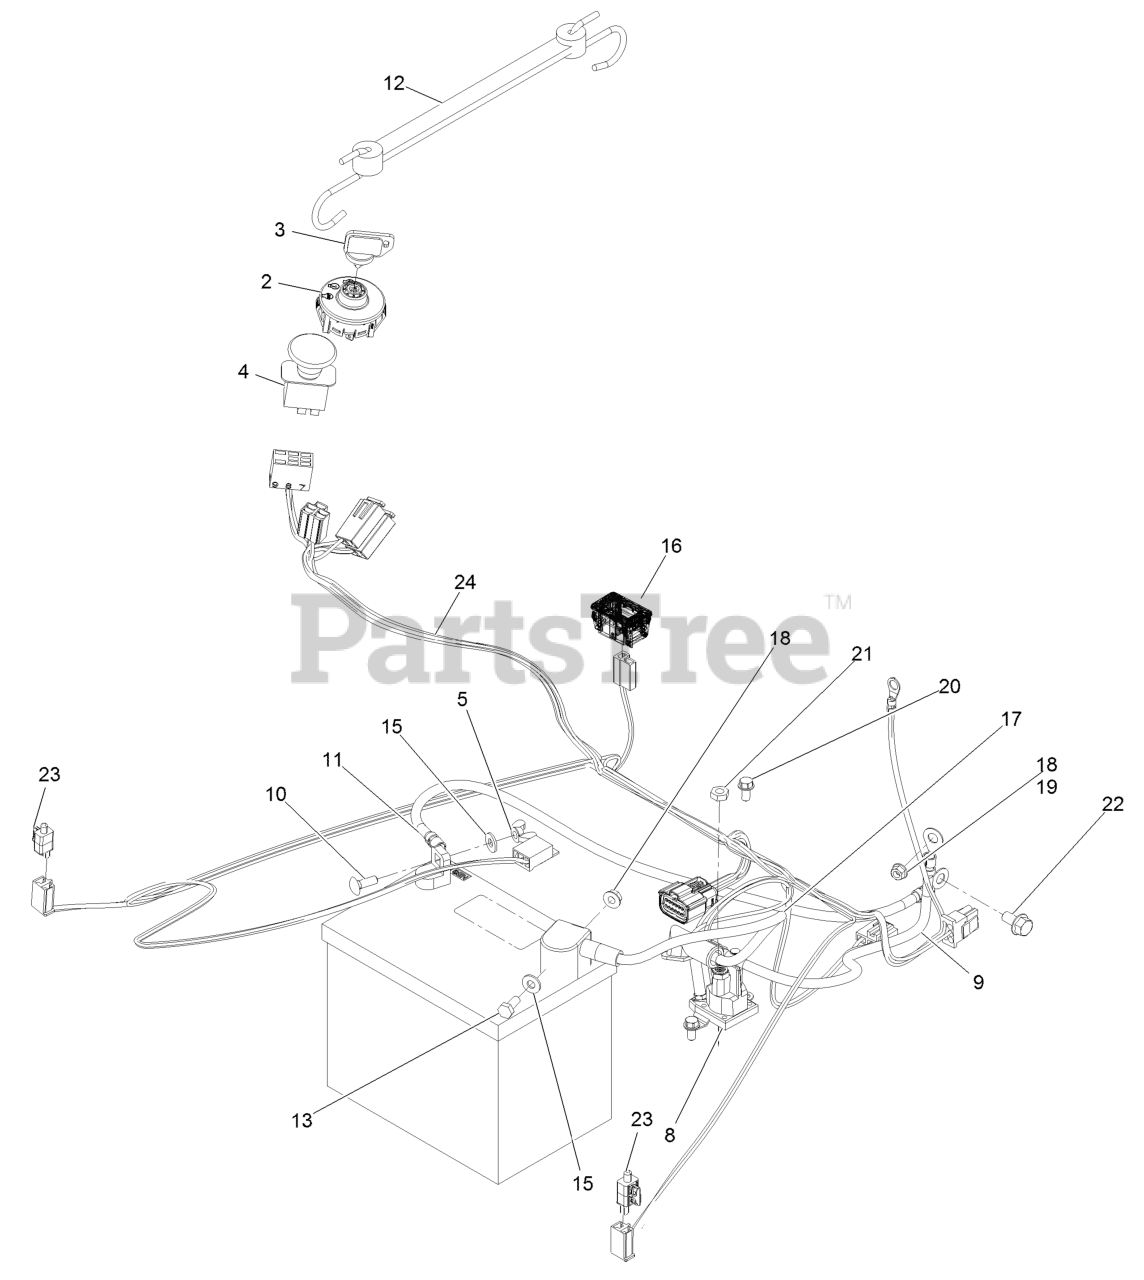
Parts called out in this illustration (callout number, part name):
1	BATTERY
3	KEY-IGNITION
4	SWITCH-PTO
5	NUT-WING
8	SOLENOID
9	CABLE-BATTERY, POSITIVE
10	BOLT-CARR
11	CABLE-BATTERY, BLACK
12	HOLDDOWN-BATTERY
13	SCREW-HH
15	WASHER-FLAT
16	HOURMETER
17	CABLE-BATTERY, RED
20	SCREW-HWH
21	NUT-JAM
22	SCREW-HHF
